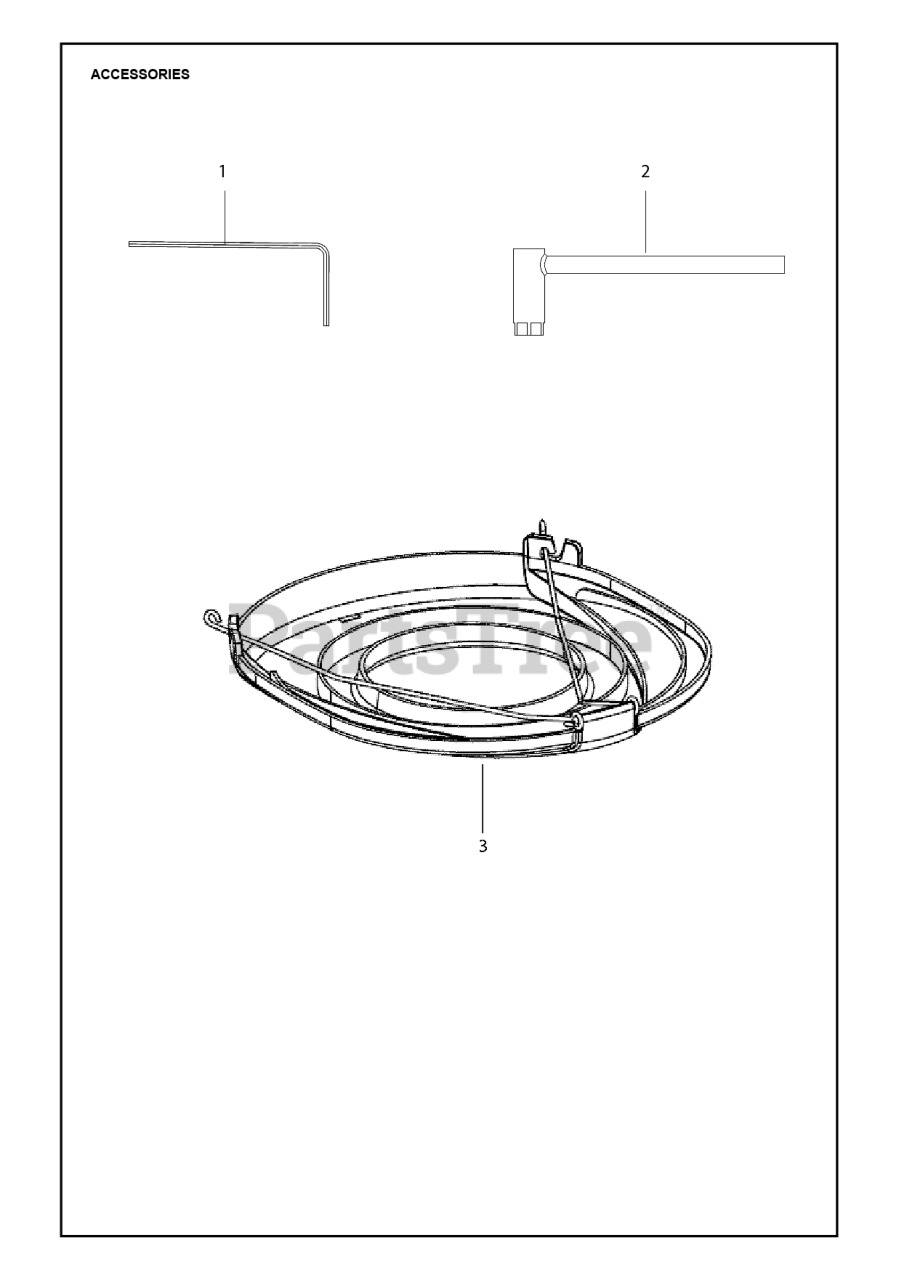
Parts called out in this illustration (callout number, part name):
1	HEX WRENCH 5/32
2	COMBI WRENCH
3	BLADE GUARD TRANSPORT
